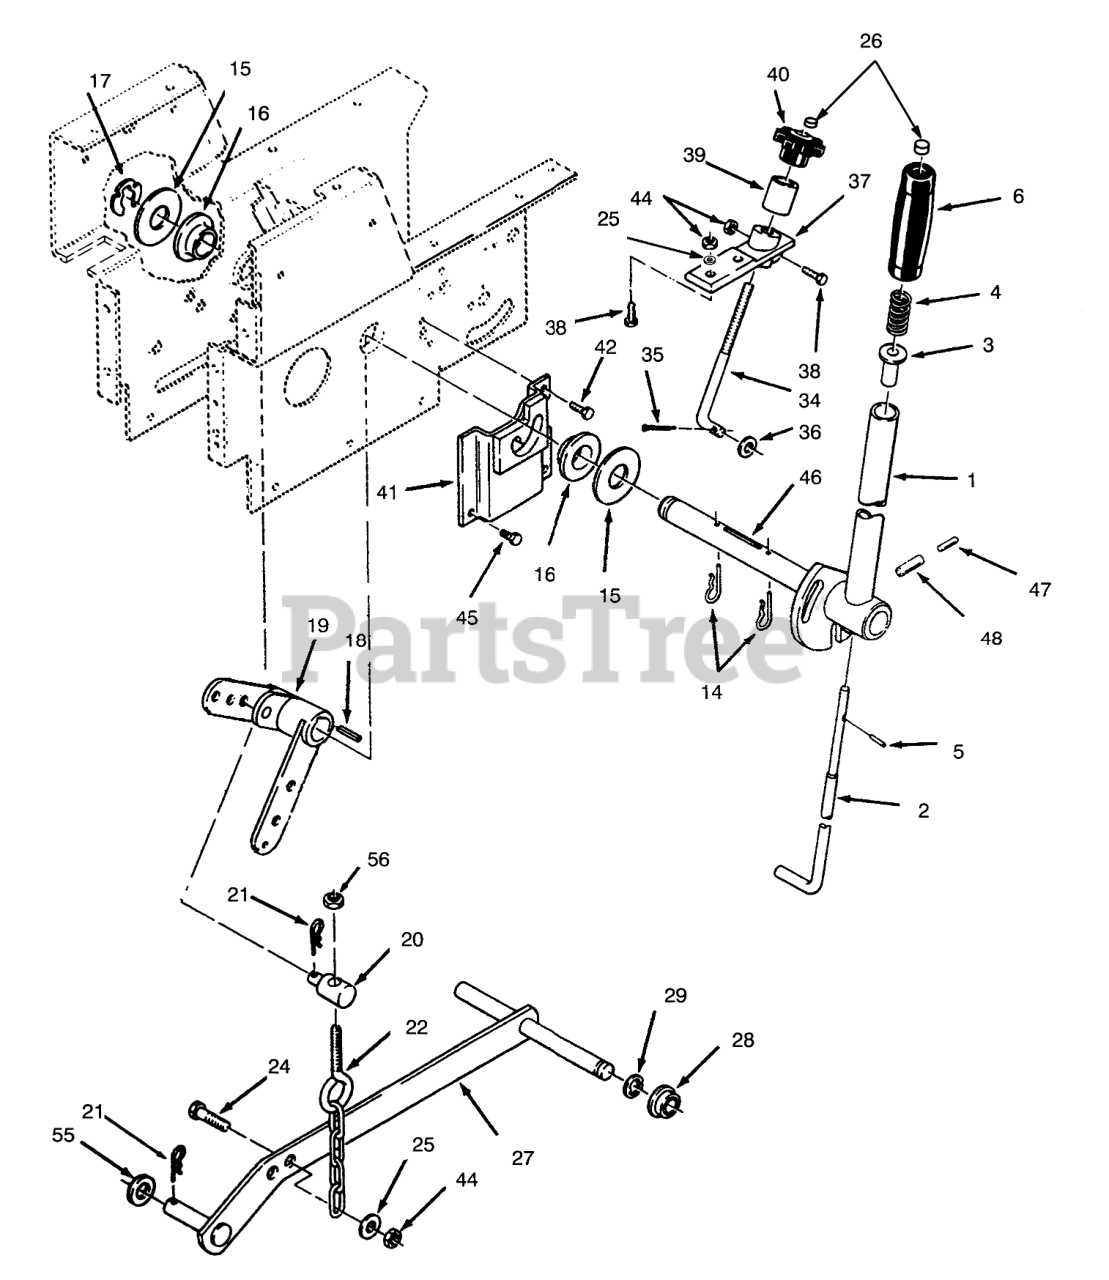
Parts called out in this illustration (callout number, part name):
1	Lever-Lift (Incl.Ref.#46,47&48)
2	ROD-LATCH LIFT
3	RETAINER-SPRING
4	SPRING-COMPRESSION
5	PIN-SPIROL
6	HANDGRIP
14	Pin-Cotter
15	WASHER-FLAT
16	BEARING-FLANGE
17	RING-RETAINING
18	KEY-SQUARE
19	LIFT LEVER ASM
20	TRUNNION-LIFT
21	Hairpin Cotter
22	CHAIN-LIFT
24	SCREW-HH
25	WASHER-PLAIN
26	CAP-ROD, PLUNGER
27	Bar-Lift
28	BUSHING
29	RING-RETAINING, EXTERNAL
34	ROD-HEIGHT CONTROL
35	PIN-COTTER
36	WASHER-FLAT
37	Casting
38	SCREW-HH
39	Sleeve
40	KNOB-LIFT CONTROL
41	Latch Bracket
42	SCREW
44	NUT-LOCK, NI
45	Bolt
46	SHAFT-LIFT LEVER
47	PIN-SPRING
48	PIN-ROLL
55	WASHER-FLAT
56	NUT-LOCK, NI
